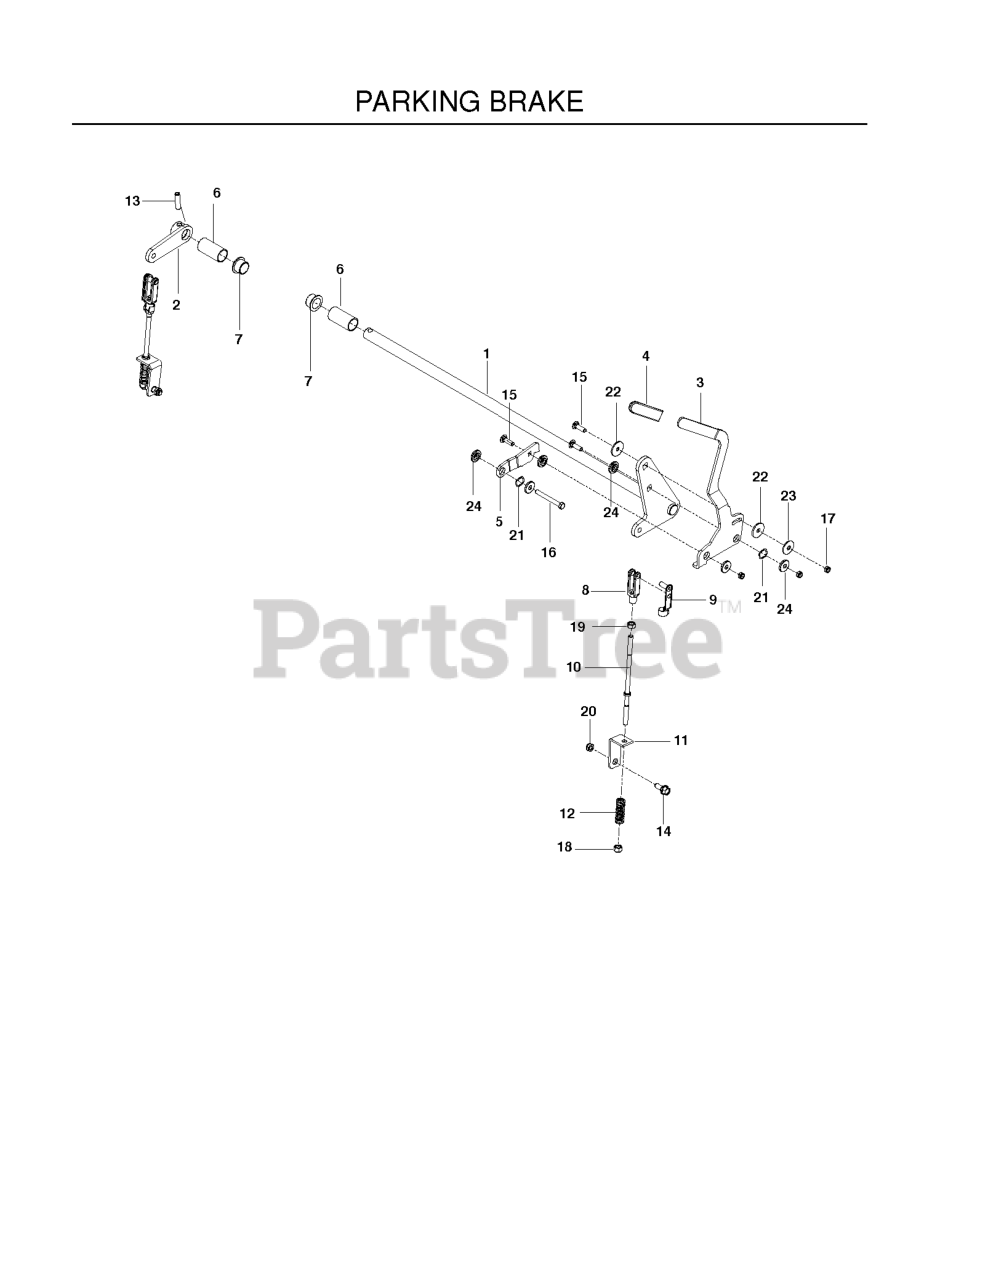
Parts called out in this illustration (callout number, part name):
1	SHAFT, BRAKE, WELDED
2	ARM, BRAKE, RT
3	LEVER.BRAKE.BLACK
5	LINK, FOLLOWER
6	SPACER, SHAFT, BRAKE
7	BEARING, FLANGE
8	YOKE 5/16 ADJ CLEVIS
9	PIN, CLEVIS SPRING, 3/8
10	LINKAGE, BRAKE
11	BRKT, BRAKE, BLK
12	SPRING, ENGAGEMENT
13	5/16 DIA ROLL PIN
14	BOLT, SHOULDER
15	RHSNB 3/8-16 X 1-1/4
16	HCS 3/8-16 X 3-1/4 GR5 ZD
17	NUT HEX 3/8-16 NYLON, THIN
18	NUT 5/16F NYLOC
20	5/16-18 THIN PROF NY
21	WASHER, .825 X 1.087, WAVE
22	WASHER, FRICTION, 1/8
23	CONE WASHER
24	BUSHING, BRAKE
